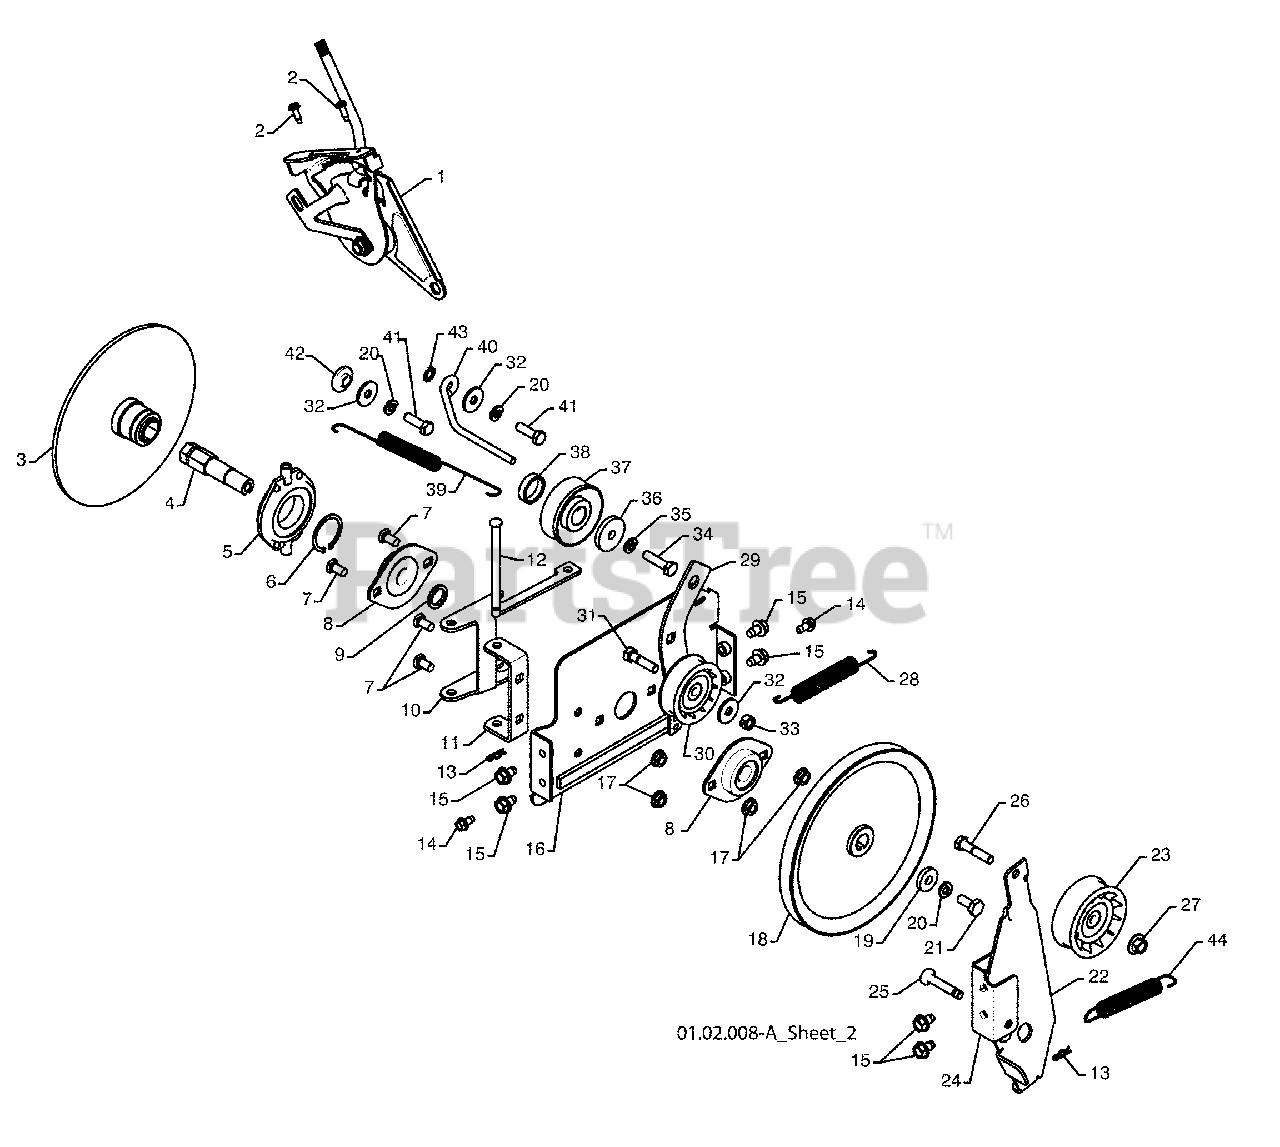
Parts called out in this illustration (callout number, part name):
1	SPEED SELECTOR HEAD ASSEMBLY
2	SCREW 10--24 X .625
3	DRIVE PLATE WELDMENT
5	TRUNNION BEARING ASSEMBLY
6	RETAINER
7	CARRIAGE BOLT 5/16--18 X .625
8	FLANGE BEARING
10	LEVER SHIFTER PLATE
11	SHIFTER SUPPORT BRACKET
14	SCREW 1/4--20 X .500
15	BOLT 5/16--18 X .500
16	DRIVE MOUNT PLATE
17	NUT 5/16--18
18	TRACTION PULLEY
20	LOCKWASHER 5/16
21	SCREW 5/16--18 X .750
22	IDLER BRAKE ARM
23	IDLER PULLEY
24	IDLER PIVOT BRACKET
26	SCREW 5/16--18 X 1.50
27	NUT 5/16--18
28	TRACTION SPRING
29	IDLER TRACTION ARM
30	IDLER PULLEY
31	SCREW 5/16--18 X 1.25
33	NUT 5/16--18
34	SCREW 3/8--24 X 1.38
35	LOCKWASHER 3/8
37	ENGINE TRACTION PULLEY
39	RETURN SPRING
40	BELT GUIDE
41	SCREW 5/16--18 X 1.00
42	BUSHING
43	LOCKWASHER 5/16
44	BRAKE SPRING
